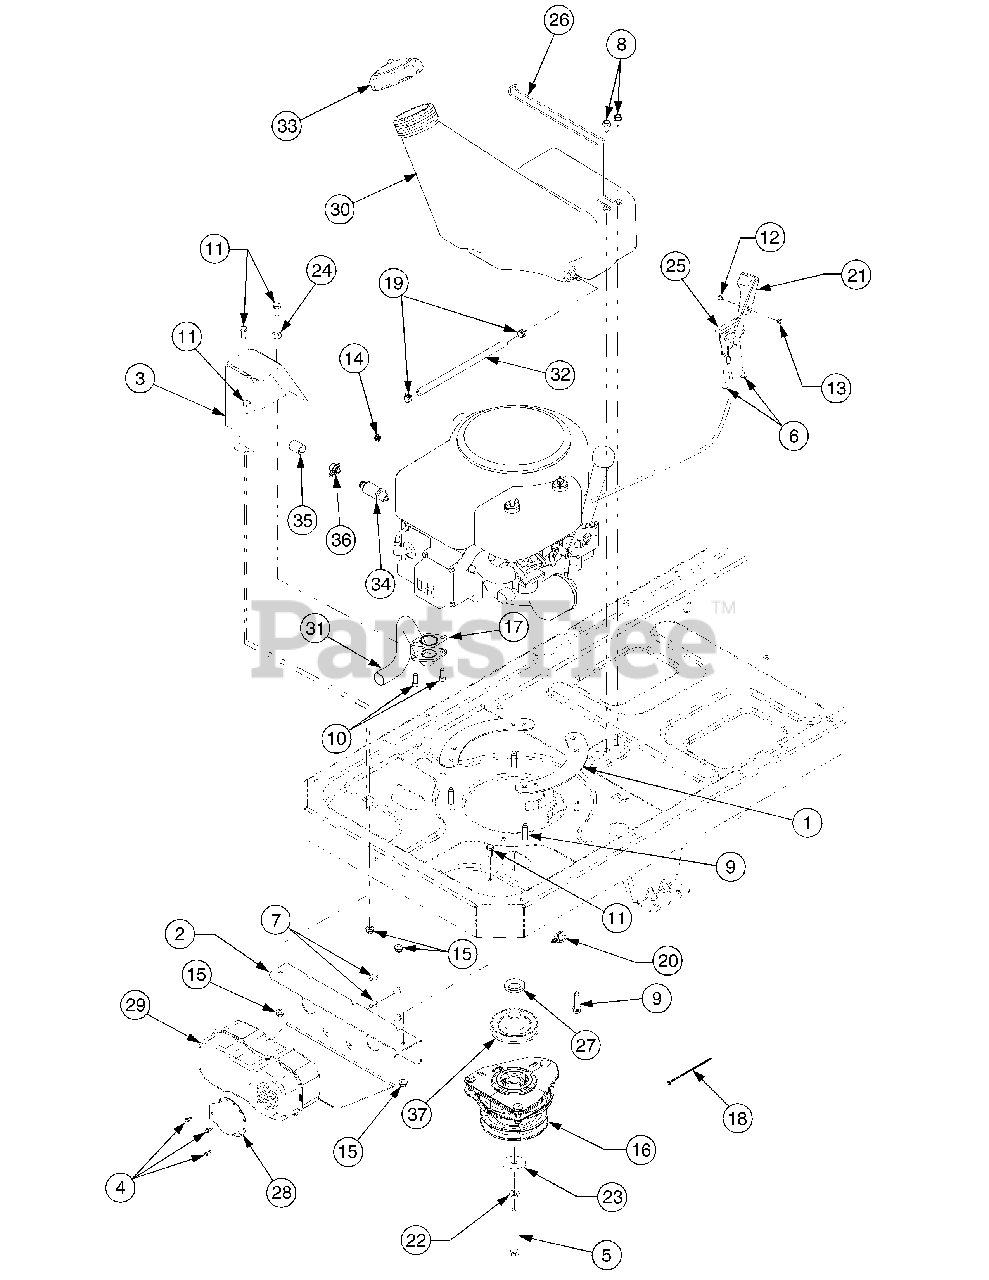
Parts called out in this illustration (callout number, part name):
2	Bracket, Muffler Mounting
3	Shield, Muffler Tube Heat
4	Screw, Hex Wash. Hd. Tapp #8-18 x .5
5	Screw, Hex Cap, 7/16-20 x 4.0 GR5
6	Screw, Hex Wash. Hd. Tapp #12-16 x .5
7	Screw, Hex Wash. Hd. Tapp 1/4-20 x .5
8	Screw, Hex Wash. Hd. Tapp 5/16-12 x .75
9	Screw, Hex Sems Wash. Hd. Tapp 3/8-16 x 1.5
10	Screw, Socket Hd. 5/16-18 x .75
11	Screw, Hex Cap, 5/16-18 x .75 GR5
12	Screw, Truss Hd. Mach. #8-32 x .375
13	Nut, Hex, #8-32
14	Nut, Sems, 1/4-20
15	Nut, Hex Insert Flange Lck, 5/16-18 GrF
16	Clutch Assembly, Electric PTO
17	Gasket, Exhaust (Tec)
20	Clip, Cable Retainer
21	Knob, Throttle Control
22	Washer, Lock, 7/16
23	Washer, Flat, .438 x 1.75 x .25
24	Washer, Flat, .344 x .75 x .12
25	Cable, Throttle, 39.0 Lg
26	Wire, Tank Mounting
27	Spacer, PTO, 1.0 x 1.62 x .21
28	Deflector, Muffler
29	Muffler
30	Tank, Fuel, 3.0 Gal.
31	Pipe, Exhaust
32	Hose, Fuel Line
33	Cap, Fuel
34	Valve, Oil Drain
35	Hose, Oil Drain Extension
36	Cap, Oil Drain Valve
37	Pulley, Drive
